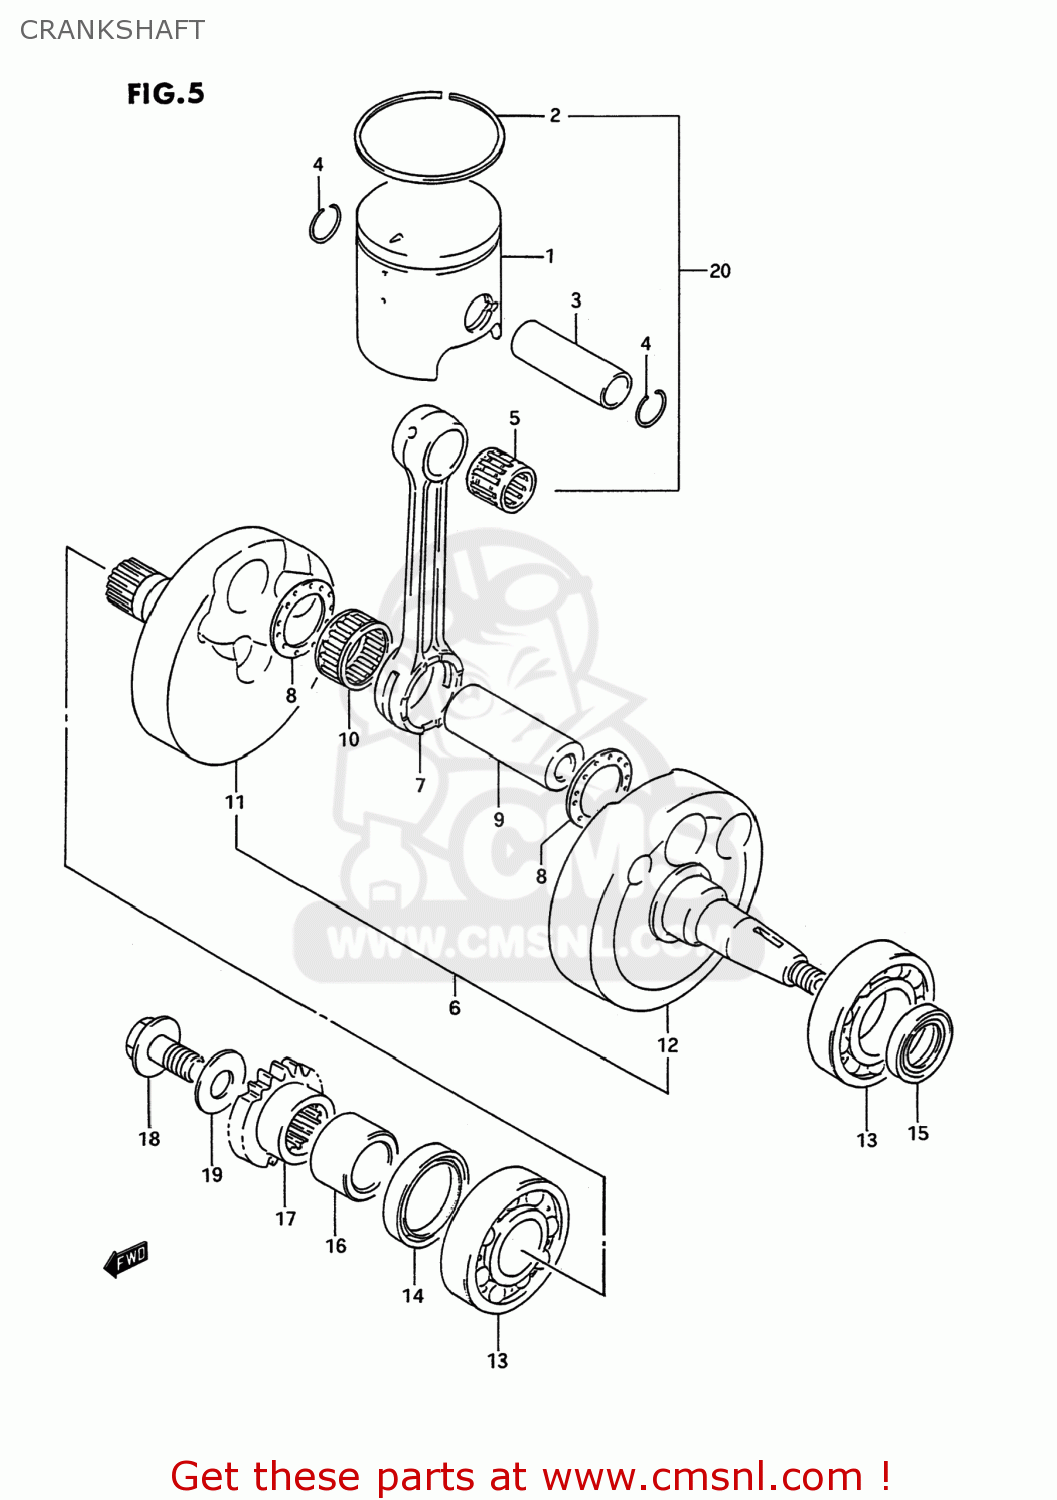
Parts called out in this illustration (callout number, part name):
1	PISTON
2	RING,PISTON
3	PIN,PISTON
4	CIRCLIP
5	BEARING(15X19X20)
6	CRANKSHAFT ASSY
7	ROD,CONNECTING
8	WASHER(22X36X1.5)
9	PIN,CRANK
10	BEARING(22X28X16)
11	CRANKSHAFT,R
12	CRANKSHAFT,L
13	BEARING(22X56X16)
14	SEAL,OIL(30X40X7)
15	SEAL,OIL(18X30X6)
16	SPACER,PRIMARY DRIVE GEAR
17	GEAR,PRIMARY DRIVE (NT:
18	BOLT,PRIMARY DRIVE GEAR
19	WASHER
20	TOP END KIT,ENGINE
